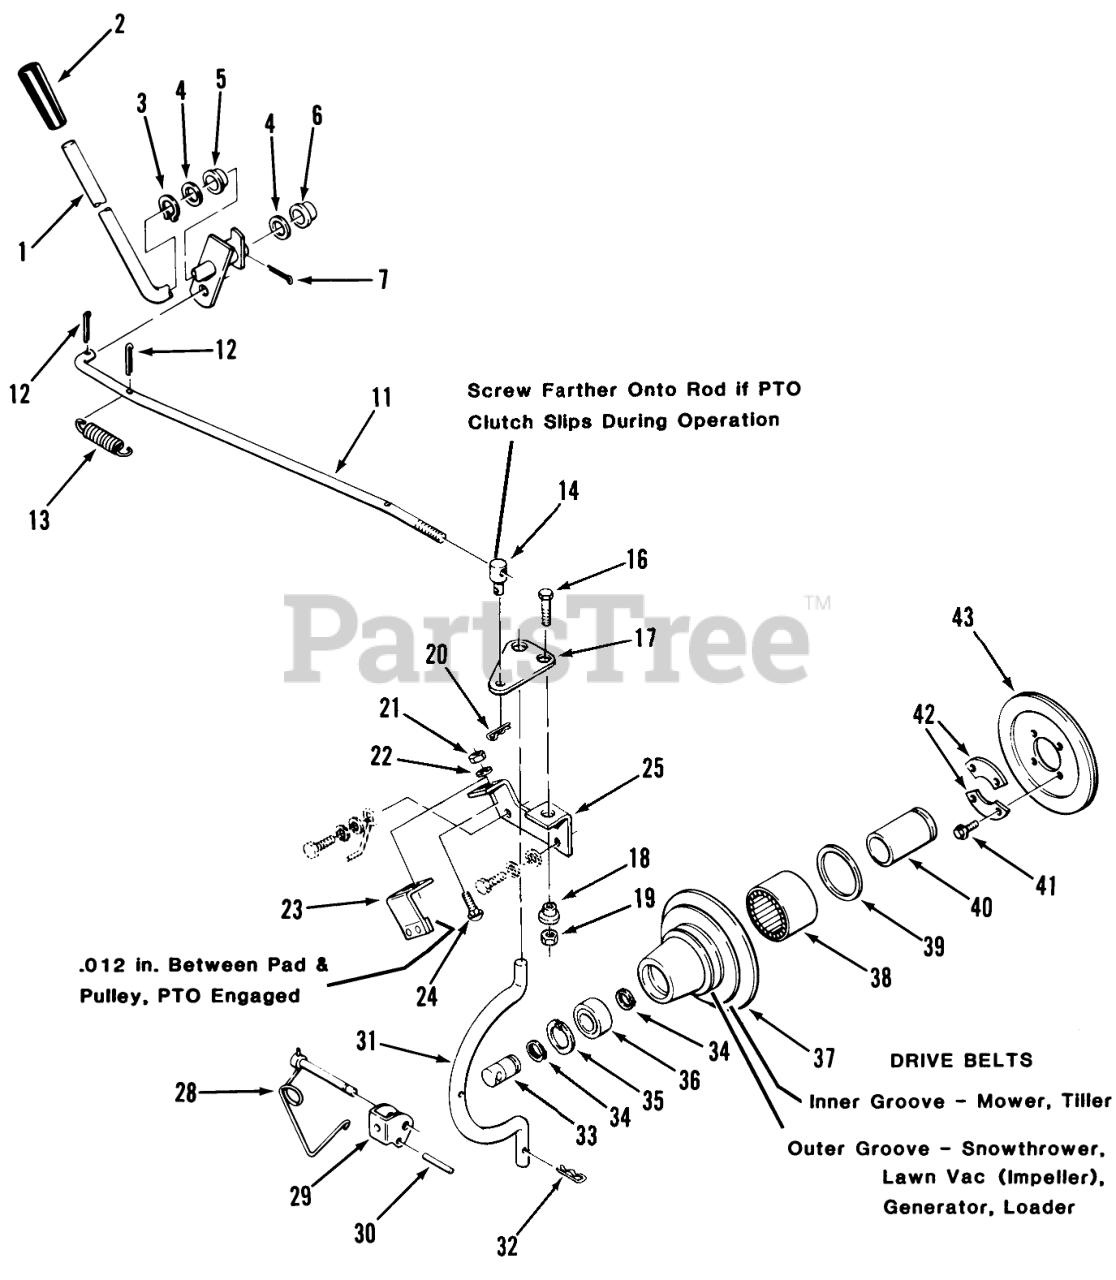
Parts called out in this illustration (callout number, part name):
1	PTO Clutch Lever
2	GRIP
3	Grip Ring
4	SHIM-WASHER
5	BUSHING-NYLINER
6	NYLINER BUSHING
7	Pop Rivet
11	PT0 Clutch Rod
12	Pop Rivet
13	SPRING
14	TRUNNION
16	BOLT
17	PLATE R
18	SPACER-BRAKE LINK
18	SPACER-LIFT LINK
19	Nut
20	Hairpin Cotter
21	Nut
23	ASSY-BRAKE
23	PTO Brake Assy
24	Bolt-Carriage
25	BRACKET-ENGINE B
28	Pin
29	Clevis
31	ROD-HOUSING (NS)
31	ROD-HOUSING
32	Hairpin
33	SHAFT-PTO
34	RING-SNAP, EXTERNAL
35	Ring-Snap
36	BaIl Bearing
37	Housing-Clutch
38	BRG-NEEDLE OPEN END
39	SEAL-OIL
40	BEARING RACE
41	H H C S
42	RETAINER
43	Clutch Plate & Facing
